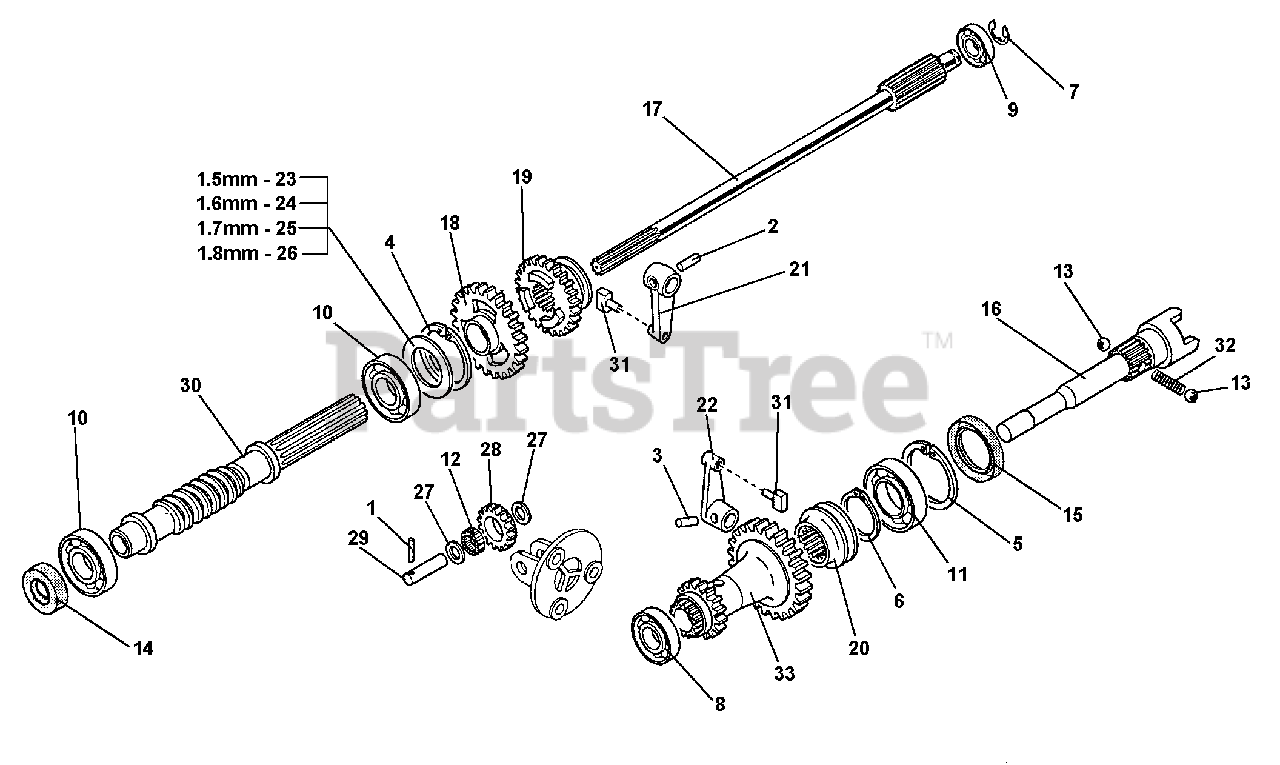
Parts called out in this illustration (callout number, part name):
1	LOCKING PIN, 2.5X22
2	LOCKING PIN, 6X24
3	LOCKING PIN, 6X20 SPIRAL
4	CIRCLIP, INTERNAL
5	CIRCLIP, INTERNAL
6	CIRCLIP, EXTERNAL
7	RETAINING RING
8	BEARING, 15X35X11
9	BEARING, 15X42X13
10	BEARING, 25X52X15
11	BEARING, 30X55X13
12	BEARING, 12X15X10
14	OIL SEAL, 15X28X7
15	OIL SEAL, 38X55X7
19	SLIDER GEAR
21	LEVER, SLIDER
22	LEVER, PTO ENGAGMENT
23	SHIM, 1.5MM
24	SHIM, 1.6MM
28	REVERSE GEAR
29	PIN, REVERSER GEAR
32	SPRING, PTO BALLS
